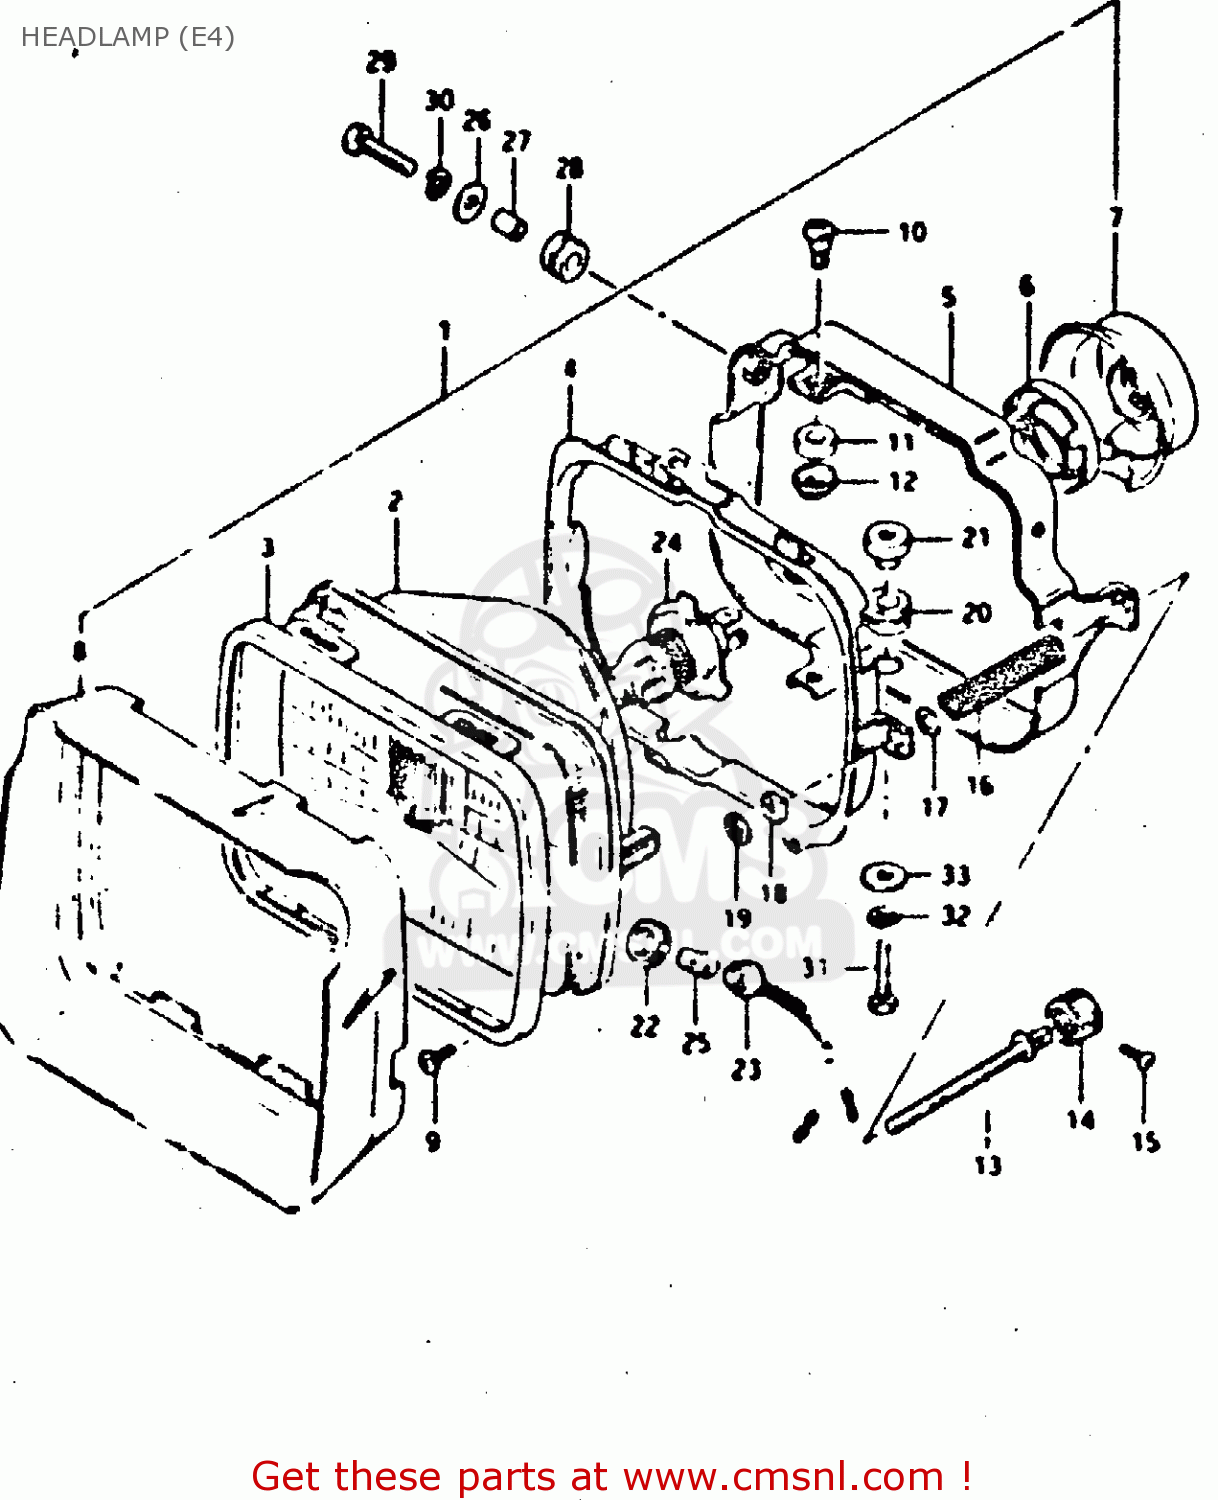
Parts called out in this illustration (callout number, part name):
1	HEADLAMP ASSY
2	LAMP UNIT
3	RETAINER
4	RING,MOUNTING
5	HOUSING
6	HOLDER
7	COVER,HEADLAMP SOCKET
8	SHADE,HEADLAMP UNIT
9	SCREW
10	SCREW
11	SPACER
12	NUT,ADJUSTING
13	SCREW,ADJUSTING
14	KNOB,ADJUSTER
15	SCREW
16	SPRING
17	WASHER
18	NUT
19	NUT,HEADLAMP ADJUSTER
20	CUSHION
21	NUT
22	JOINT,RUBBER
23	SOCKET
24	BULB (12V, 60/55W, H4)
25	BULB(12V4W)
26	WASHER
27	SPACER (6.1X8X9.5)
28	CUSHION
29	BOLT
30	LOCK WASHER
31	SCREW(6X20)
32	LOCK WASHER
33	WASHER
